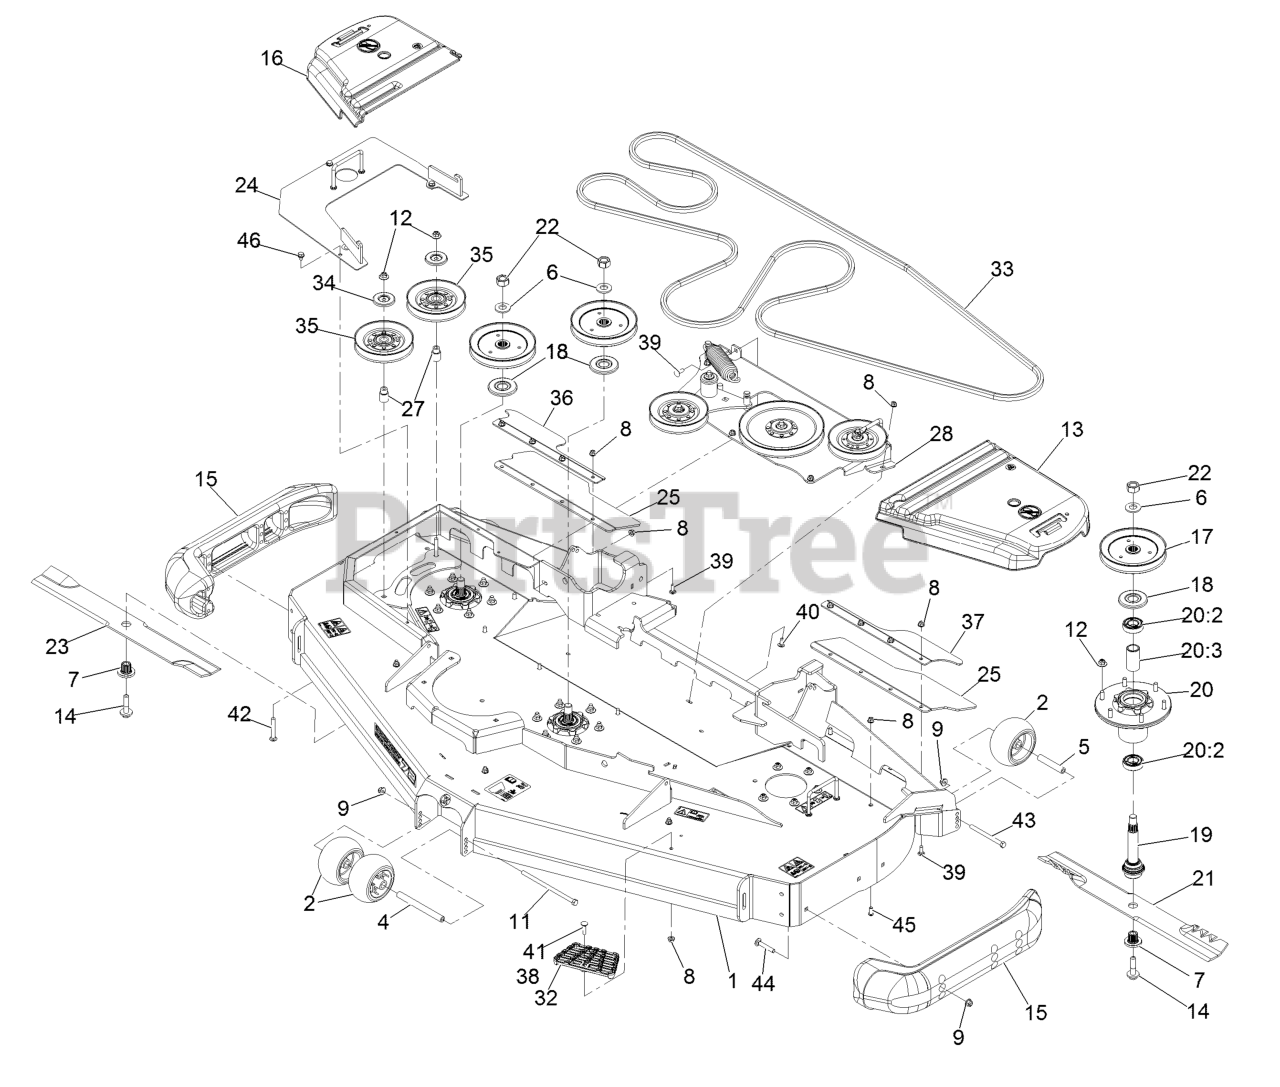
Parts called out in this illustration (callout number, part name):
1	Deck-Rd72 W/Decals
2	Roller-Scalp, Anti
4	Spacer-Wheel
5	Tube-Spanner
6	Washer-Spring Disc 3/4
7	Bushing, Splined
8	Nut-Nyloc 5/16-18 Flg
9	Nut-Nyloc 3/8-16 Flg
11	Screw-HH 3/8-16 X 7 3/8
12	Nut-Nyloc 3/8-16 Flg
13	Cover-Belt, LH
14	Screw-Sems 1/2-20 X 2.19
15	Skid-Bumper, Deck
16	Cover-Belt, RH
17	Sheave,Blade Drive 6.50
18	Guard,Bearing Top .989
19	ASM-Spindle And Seal
20	ASM-Cutter Hsg With Bearings
20:2	Bearing-Ball
20:3	Spacer-Bearing
21	Blade-Extreme 2, 24.50"
21	Blade, Notched (72")
21	Blade, Low Lift (72")
22	Nut-Hex
23	Blade-Low Lift 24.50, Rd72
23	Blade-Extreme 2-24.50, Rd72
24	Cover-Reverse Drive
25	Guard-Tire
27	Standoff-Idler
28	Idler Mount ASM
32	Step-Deck
33	Belt-Bb
34	Shield-Dust
35	Idler V
36	Support-Flap, Outer (RH)
37	Support-Flap, Outer (LH)
38	Bolt-Carriage 5/16-18 X 1 1/4
39	Bolt-Carriage 5/16-18 X 7/8
40	Bolt-Carriage 5/16-18 X 3/4 Short Neck
41	Bolt-Carriage 5/16-18 X 1 1/4
42	Bolt-Carriage 3/8-16 X 2 1/2
43	Screw-HH 3/8-16 X 4-1/2
44	Bolt-Carriage 3/8-16 X 2 1/4
45	Screw-Button Head 5/16-18 X 3/4
46	Screw-HWH 5/16 X 1/2 Tf
